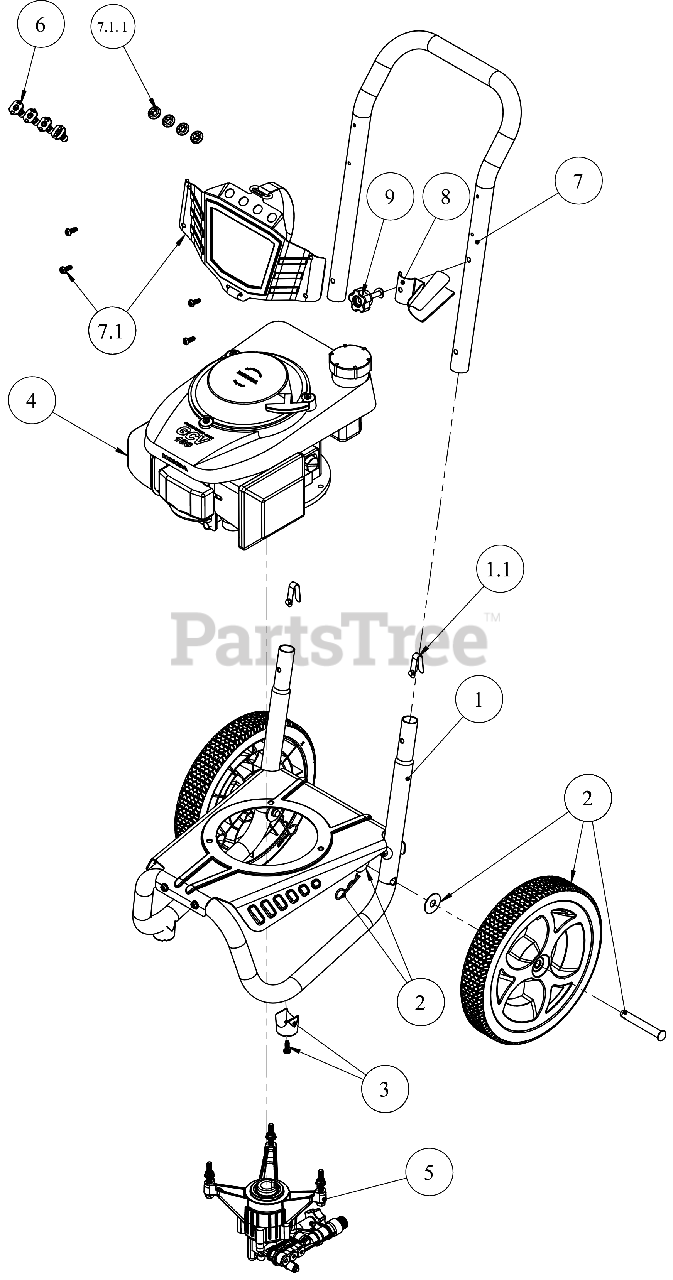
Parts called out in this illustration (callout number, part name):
1	FRAME BASE (YELLOW)
1.1	HANDLE SNAP BUTTON
2	WHEEL KIT-12"
3	FOOT PAD KIT
4	COMPLETE ENGINE
5	PUMP (SVC 510020)
6	4 PIECE NOZZLE SET
7	UPPER HANDLE (YELLOW)
7.1	DASH BOARD PANEL (W/LBL) (PW3024H)
7.1.1	SPRAY NOZZLE HOLDER
8	SPRAY GUN HOLDER
9	KNOB-HANDLE MTG
